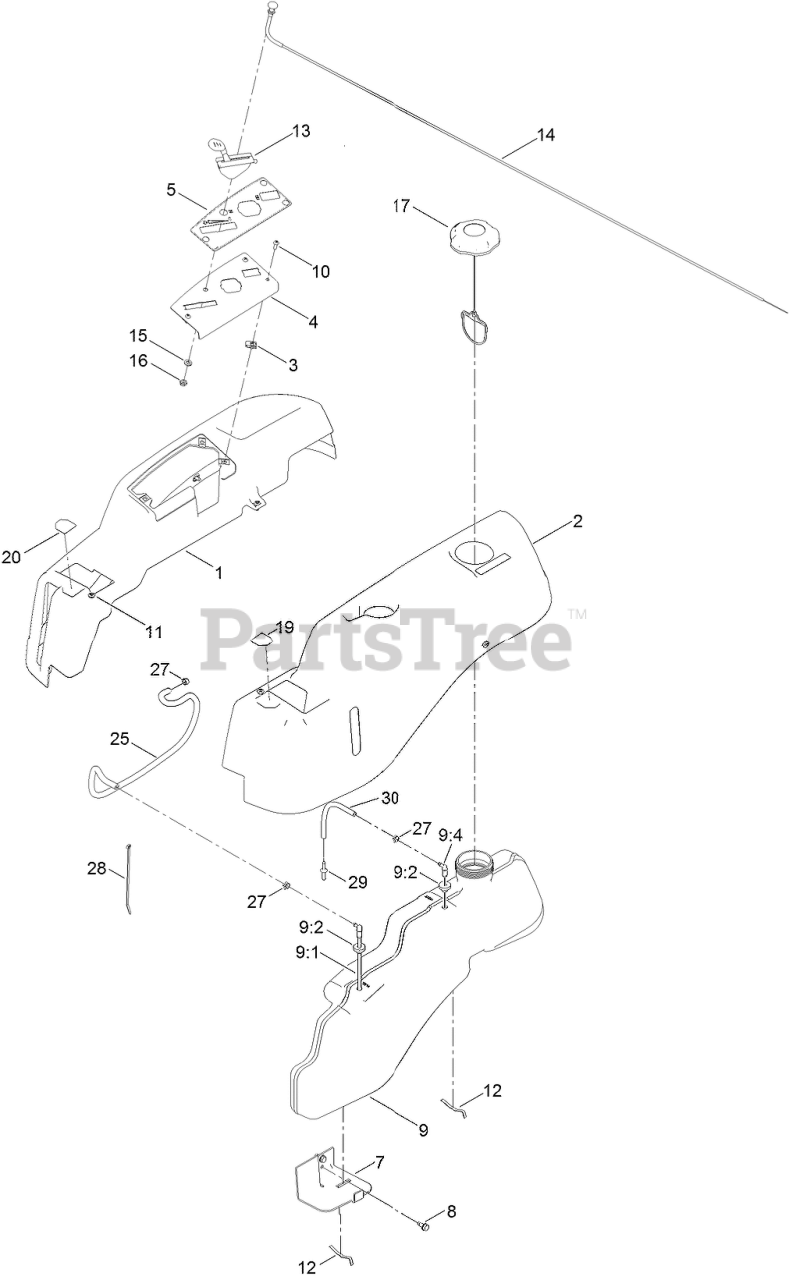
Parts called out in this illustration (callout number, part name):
1	POD-RH
2	POD-LH
4	PLATE-CONTROL
5	DECAL-PANEL, CONTROL
7	SUPPORT-TANK, FRONT
8	SCREW-HWHTF
9	FUEL TANK ASM
9:1	CONNECTOR-ELBOW, 90 DEG
9:2	BUSHING
9:4	FITTING-PLASTIC
10	SCREW-PRH
11	SCREW-SHOULDER
12	SPRING
13	CABLE-THROTTLE
14	CABLE-CHOKE
15	WASHER-LOCK
16	NUT-HJ
17	CAP-FUEL, RATCHETING
19	DECAL-LEVER, CONTROL (LH)
20	DECAL-LEVER, CONTROL (RH)
25	HOSE-FUEL
27	CLAMP-HOSE
28	TIE-CABLE
29	ADAPTOR-ORIFICE
30	HOSE-FUEL
